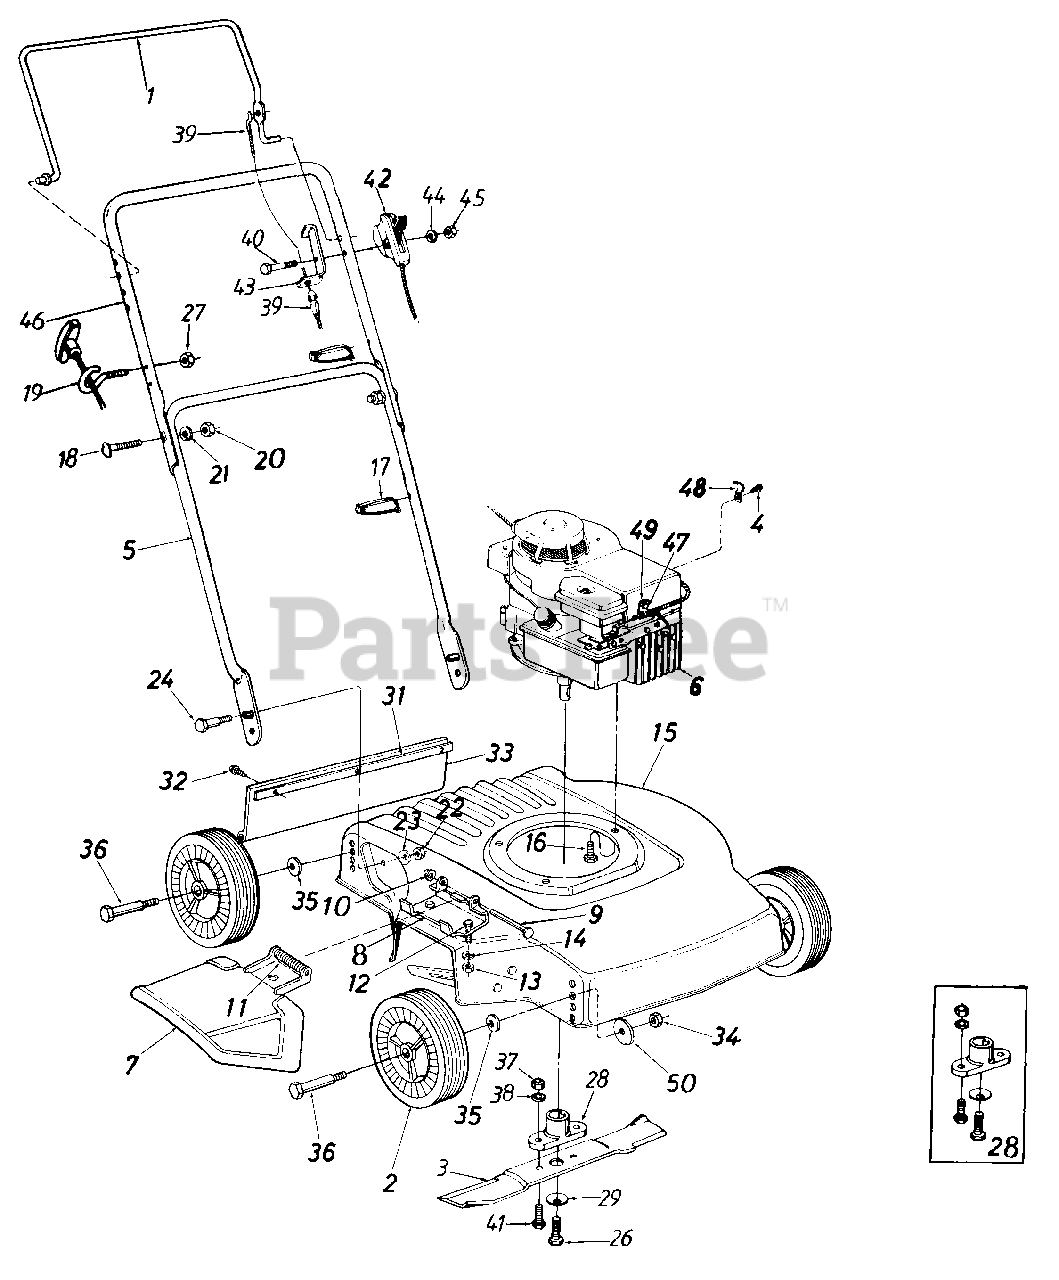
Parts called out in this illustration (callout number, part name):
1	Control Handle-L.H.
3	18" Blade
4	Hex Wash. Hd. AB-Tap Scr. #8 x .50" Lg.
5	Lower Handle
6	Engine
7	Chute Deflector Ass'y. Comp.
8	Adapter Plate
9	Pivot Pin
10	Push Nut 1/4" Rod
11	Torsion Spring
12	Hex Bolt "4-20 x .50" Lg.
13	Hex Nut 1/4-20 Thd.*
14	L-Wash. 1/4" I.D.*
15	18" Deck Ass'y.
16	Hex Wash. Hd. TT-Tap Scr. 3/8-16 x 1.00" Lg.
17	Cable Tie
18	Curved Carriage Bolt 5/16-18 x 1.38" Lg.
19	Rope Guide
20	Hex Nut 5/16-18 Thd.*
21	L-Wash. 5/16" I.D.*
22	Hex Ins. L-Nut 5/16-18 Thd.
23	Bell-Wash. .345" I.D. x .88"
24	Shoulder Bolt .437" Dia. x .180
26	Hex Bolt 3/8-24 x 1.5" Lg. (Grade 5)
27	Hex L-Nut 1/4-20 Thd.
28	Blade Adapter Kit
29	Bell-Wash..39" I.D.
31	Retaining Strip
32	Hex Wash. Hd. AB-Tap Scr. 1/4" x.62" Lg.
33	Rear Flap Ass'y.
34	Hex Nut 3/8-16 Thd.
35	Bell-Wash. .400" I.D. x .88" O.D.
36	Shld. Bolt .498" Dia. x 1.450" Lg.
37	Hex L-Nut 3/8-24 Thd.
38	L-Wash. 3/8" I.D.
39	Control Cable-36"
40	Hex Bolt 1/4-20 x 1.875" Lg.
41	Hex Bolt 3/8-24 x 1" Lg.
42	Throttle Control Ass'y. Comp.
43	Cable Mounting Brkt.
44	Spr. Wash. .27" I.D. x .57" O.D.
45	Hex Nut 1/4-20 Thd.
46	Upper Handle
47	Hex B-Tap Scr. #10 x .38" Lg.
48	Casing Clamp
49	Casing Clamp
50	Fl-Wash. .398" I.D. x 1.13"
